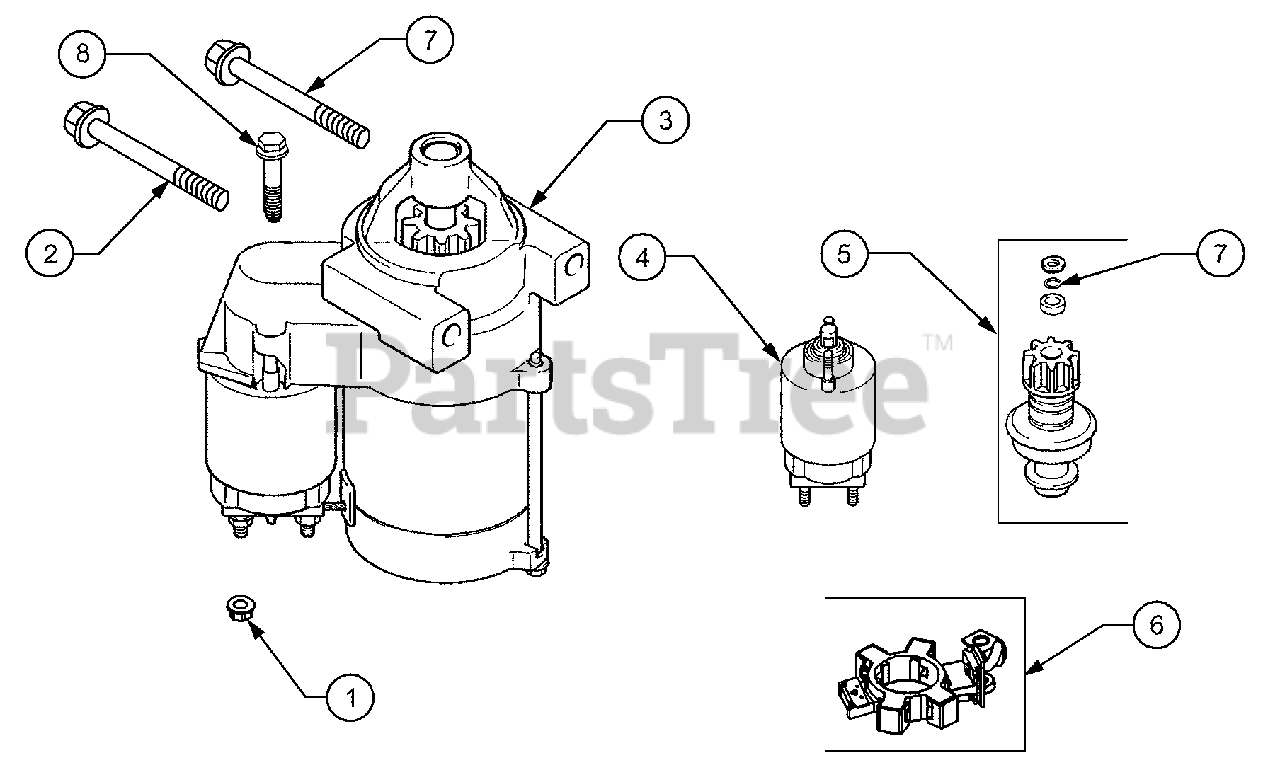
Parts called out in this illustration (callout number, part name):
1	Nut, Hex Flange M8 x 1.25"
2	Screw, Hex Flange M8 x 1.25 x 80
3	Starter, Solenoid Shift Assembly
4	Kit, Solenoid
5	Kit, Pinion Drive
7	Ring, Retainer
8	Screw, External Torx Hd.
